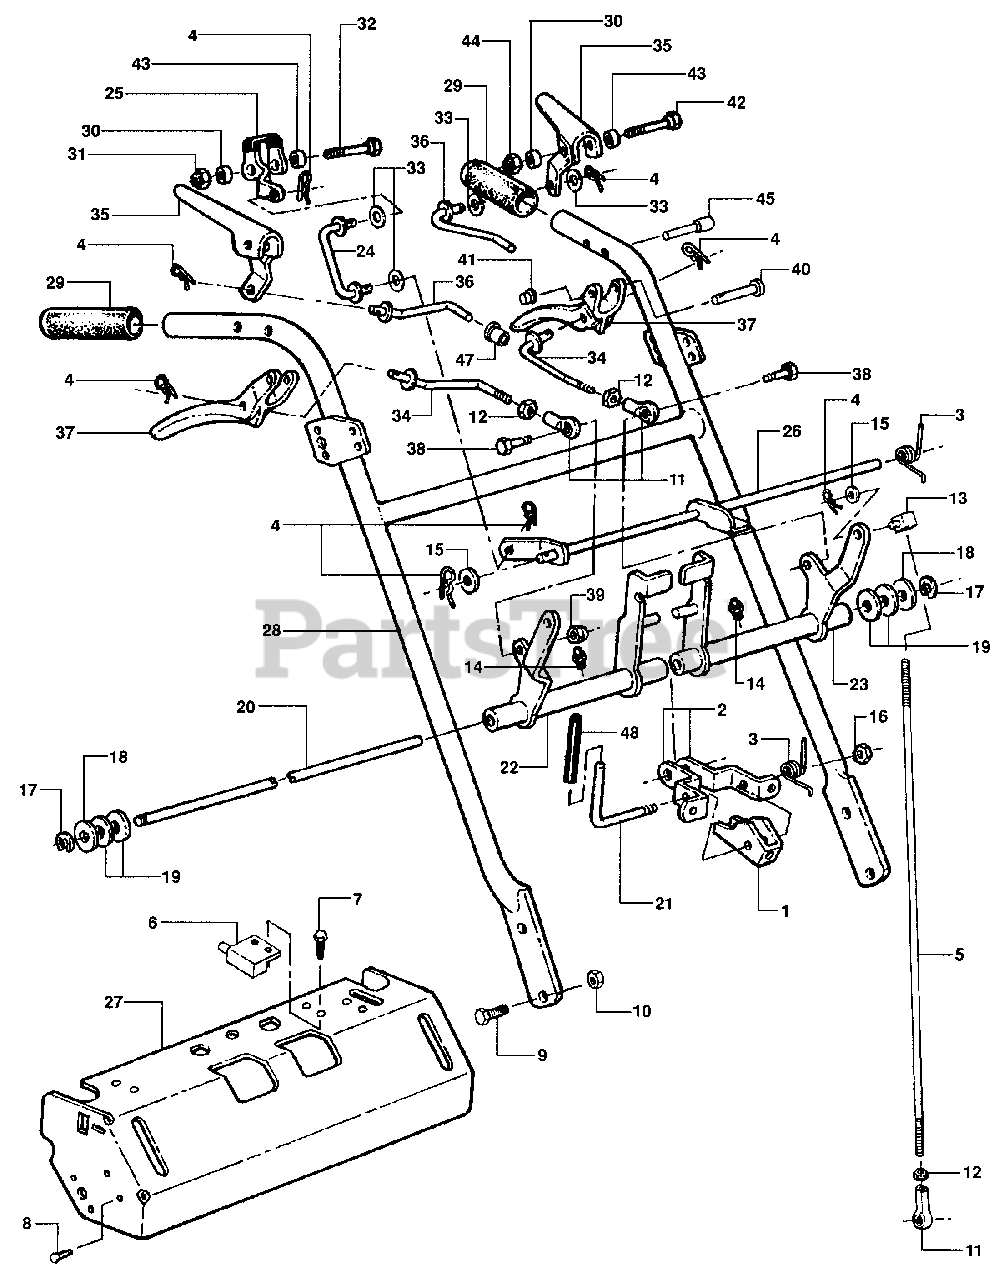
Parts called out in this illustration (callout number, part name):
1	LATCH
2	BRACKET, Neutral Mounting
3	SPRING, Neutral Torsion
4	PIN, Hair
5	ROD, Traction
6	SWITCH
7	SCREW, #12-14 x 1/2" Self-Tapping
8	SCREW, 1/4-20 x 112" Self-Tapping
9	SCREW, 3/8-16 x 1" Hex Head Cap
10	NUT, 3/8-16 Hex (Nyloc)
11	BALL JOINT LINKAGE, 5/16-24
12	NUT, 5/16-24 Hex
13	SWIVEL
14	FITTING, 1/4-28 Zerk
15	WASHER, 3/8" Flat
16	NUT, 1/4-20 Hex (Nyloc)
17	"E" RING 112
18	BUSHING 1/2 Machinery
19	WASHER, 1/2 Flat
20	ROD, Pivot
21	INDICATOR, Neutral
22	WELDMENT, Speed Control (Left Hand)
23	WELDMENT, Speed Control (Right Hand)
24	ROD, Neutral Release
25	RELEASE, Neutral
26	WELDMENT, Neutral Paddle
27	CONSOLE (Pistol Grip)
28	WELDMENT, Handle
29	GRIP
30	SPACER, .259 ID x .78" Long (NLA)
31	NUT, 1/4-20 Hex Lock
32	SCREW, 1/4-20 x 2-3/4"
33	WASHER, 5/16 x 1/2" O.D. (Stainless)
34	ROD, Drive (Left Hand)
35	WELDMENT, OPC (Left Hand)
36	ROD, OPC (Left Hand)
37	LEVER, Drive
38	SCREW, 5/16-18 x 1"
39	NUT, 5/16-18 Hex (Nyloc)
40	PIN, 3/16 x 1-3/4" Clevis
41	NUT, 3/16 Push
42	BOLT, 1/4-20 x 2-3/4"
43	BUSHING
44	NUT, 1/4-20 Hex
45	PIN, 5/16 x 1-1/8" Split
47	BUSHING 5/16 (Plastic)
48	GRIP, Neutral Latch Red
